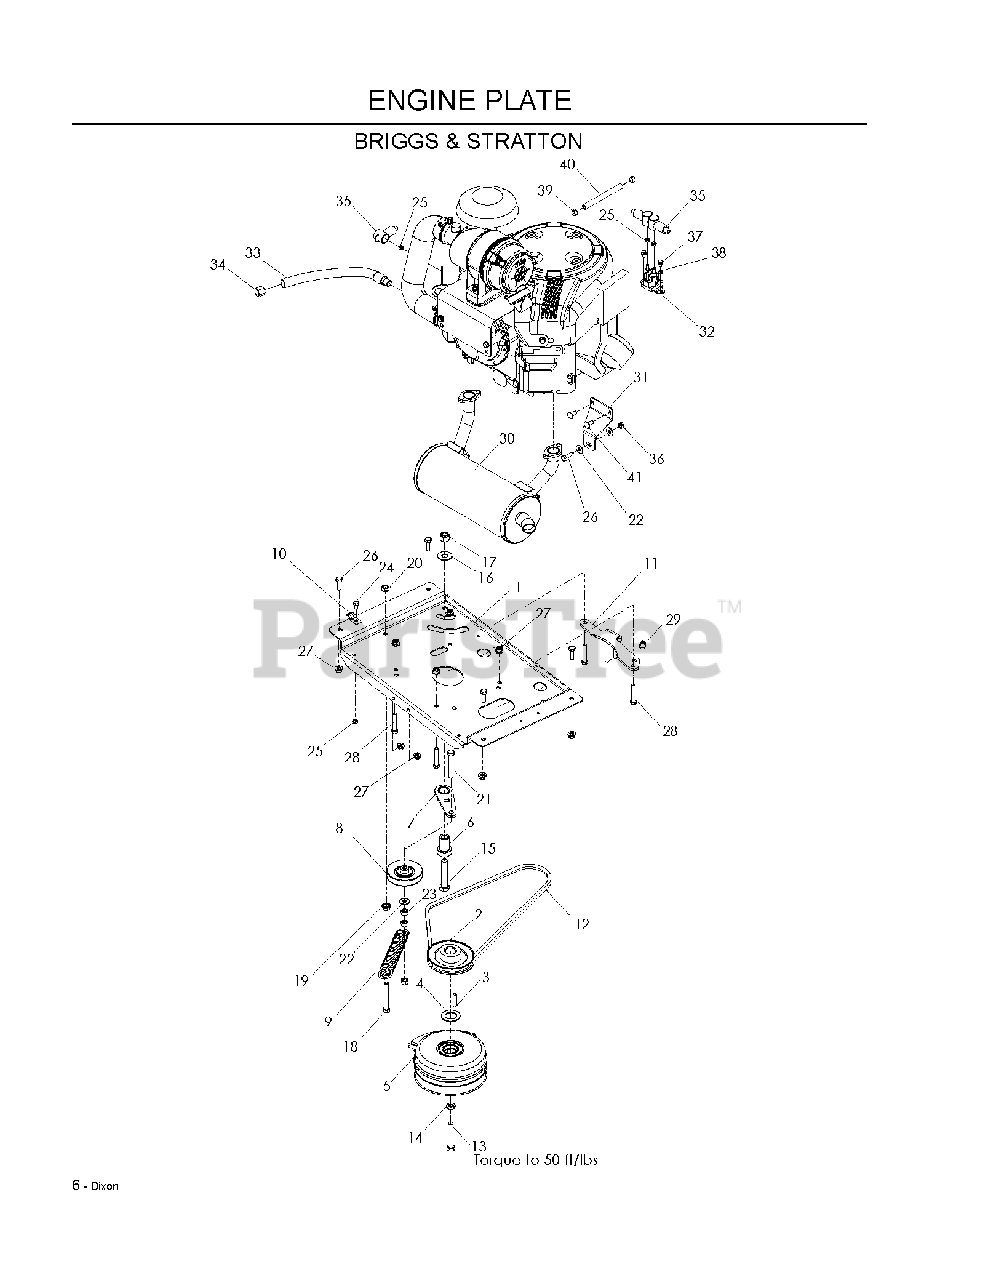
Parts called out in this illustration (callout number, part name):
1	PLATE, ENGINE, BLK
3	KEY, 1/4 SQ X 1 1/4
4	WASHER, 1.025 ID X 1.64
5	CLUTCH, 200 FT/LB
6	IDLER SPINDLE
7	IDLER ARM WELDMENT
8	PULLEY, IDLER 3 METAL
11	STOP, CLUTCH, BLK
12	BELT, "A", 44.0"
13	BOLT 7/16F X 2 1/2
14	WASHER 7/16 LOCK
15	HCS 1/2C X 2 3/4
16	WASHER 1/2 FLAT
17	NUT 1/2-13 HEX NYLOC ZD
18	SCREW 3/8C X 2 3/4 HEX CAP
19	NUT 3/8C WHIZ
20	NUT 3/8C CENTERBLOCK
21	HCS 3/8-16 X 2-1/2 TPBLT
22	WASHER 5/16 FLAT
23	NUT 3/8-16 NYLOC
24	HCS 1/4-20.
25	JAM NUT 1/4C
26	HCS 5/16C X 1
27	5/16-18 NYLOC FLANGE NUT
28	HCS 5/16C X 1 3/4
29	TIE, PLASTIC
30	MUFFLER.VANGUARD.23HP
31	MOUNT, VANGUARD MUFFLER, BLK
32	SOLENOID
33	OIL DRAIN HOSE
34	DRAIN CAP
35	INSULATOR
36	NUT 5/16C CENTERLOCK
37	HWST 1/4C X 3/8
38	WASHER 1/4 INT TOOTH
39	HOSE CLAMP
40	FUEL LINE 5"
41	BOLT 5/16C X 3/4" CARRIAGE
